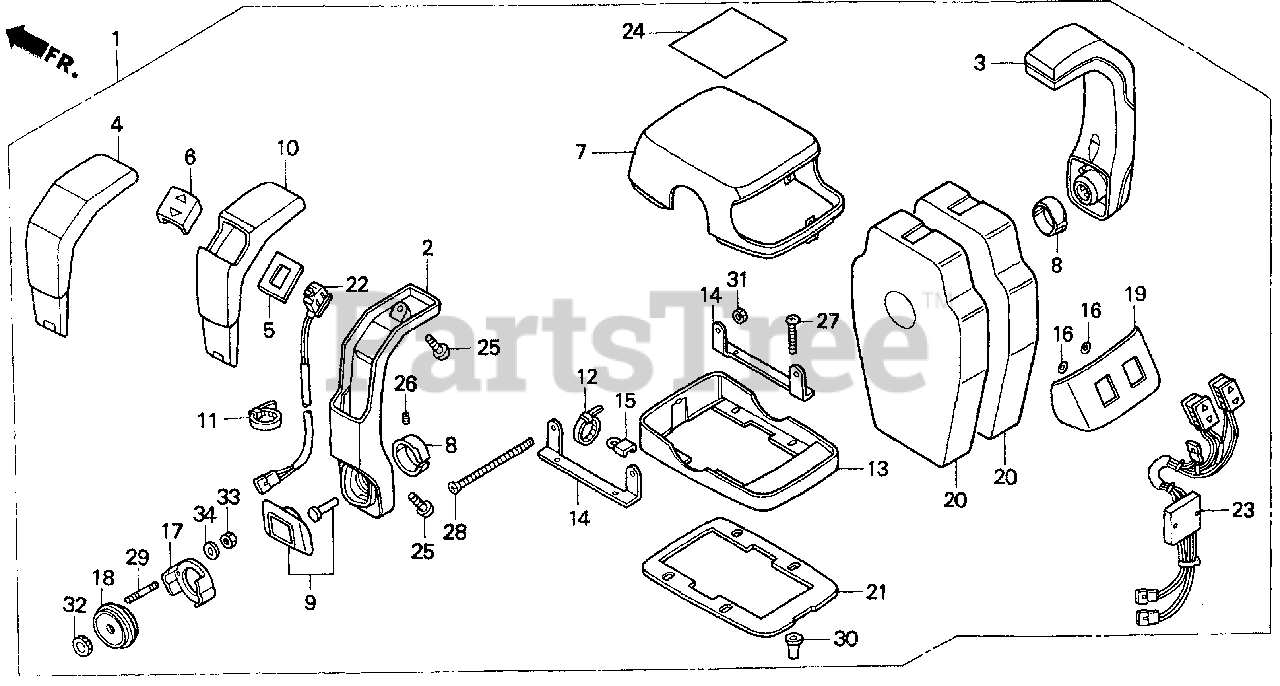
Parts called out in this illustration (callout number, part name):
1	BOX ASSY., REMOTE CONTROL (TOP MOUNT DUAL) Use up to Frame SN 1000150.
2	HANDLE ASSY., REMOTE CONTROL Use up to Frame SN 1000150.
3	HANDLE, REMOTE CONTROL Use up to Frame SN 1000150.
4	GRIP, REMOTE CONTROL HANDLE Use up to Frame SN 1000150.
5	PLATE, SWITCH SETTING Use up to Frame SN 1000150.
6	COVER, GRIP Use up to Frame SN 1000150.
7	HOUSING ASSY., REMOTE CONTROL BOX (A) Use up to Frame SN 1000150.
8	BUSHING Use up to Frame SN 1000150.
9	BUTTON ASSY. Use up to Frame SN 1000150.
10	GRIP, REMOTE CONTROL HANDLE (L) Use up to Frame SN 1000150.
11	BAND A, CABLE Use up to Frame SN 1000150.
12	BAND B, CABLE Use up to Frame SN 1000150.
13	HOUSING ASSY., REMOTE CONTROL BOX (B) Use up to Frame SN 1000150.
14	BRACKET, REMOTE CONTROL HOUSING Use up to Frame SN 1000150.
15	ANCHOR Use up to Frame SN 1000150.
16	RING Use up to Frame SN 1000150.
17	BRACKET, SWITCH MOUNTING Use up to Frame SN 1000150.
18	PLATE ASSY., SWITCH MOUNTING Use up to Frame SN 1000150.
19	MARK, REMOTE CONTROL HOUSING Use up to Frame SN 1000150.
20	HOUSING ASSY. (INNER) (TOP MOUNT) Use up to Frame SN 1000150.
21	GASKET Use up to Frame SN 1000150.
22	SWITCH ASSY., POWER TRIM-TILT (A) Use up to Frame SN 1000150.
23	SWITCH ASSY., POWER TRIM-TILT (B) Use up to Frame SN 1000150.
24	MARK, REMOTE CONTROL (DUAL) Use up to Frame SN 1000150.
25	SCREW (10-32X1") Use up to Frame SN 1000150.
26	SCREW SET (1/4-20X16") Use up to Frame SN 1000150.
27	SCREW (10-32X1-1/2") Use up to Frame SN 1000150.
28	SCREW (10-32X4") Use up to Frame SN 1000150.
29	STUD (10-32X2") Use up to Frame SN 1000150.
30	NUT, WELDING (10-32) Use up to Frame SN 1000150.
31	NUT (10-32) Use up to Frame SN 1000150.
32	NUT, LOCK (15/32-32) Use up to Frame SN 1000150.
33	NUT (10-32) Use up to Frame SN 1000150.
34	WASHER Use up to Frame SN 1000150.
